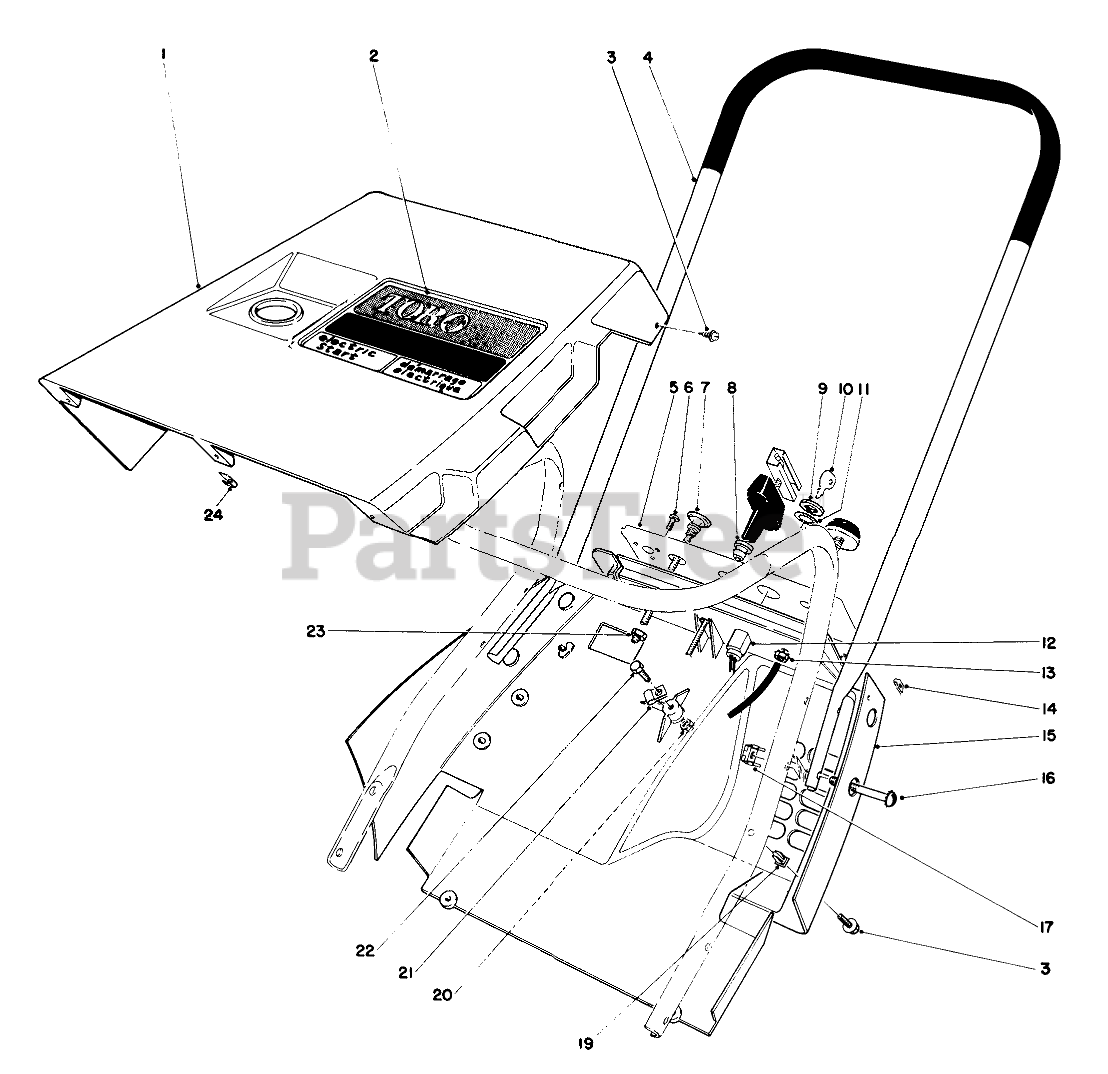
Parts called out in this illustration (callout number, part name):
1	Upper Shroud
2	Decal-Toro
3	SCREW-HWHTF
4	Upper Handle
5	Decal-Control Panel
6	SCREW-PLASTITE
7	Choke Cable
8	GUIDE-ROPE, STARTER
9	NUT-HH
10	Key
11	WASHER-TOOTH, INTERNAL
12	SWITCH-ON / OFF
13	NUT-KEPS
14	NUT-TYPE J
15	LOWER SHROUD
16	Sems Mach. Screw
17	TINNERMAN NUT
19	Push Nut
20	NUT-LOCK, NI
21	3/16 SUPPORT
22	SCREW-SHWH
23	PAL NUT/CHOKE CNTRL
